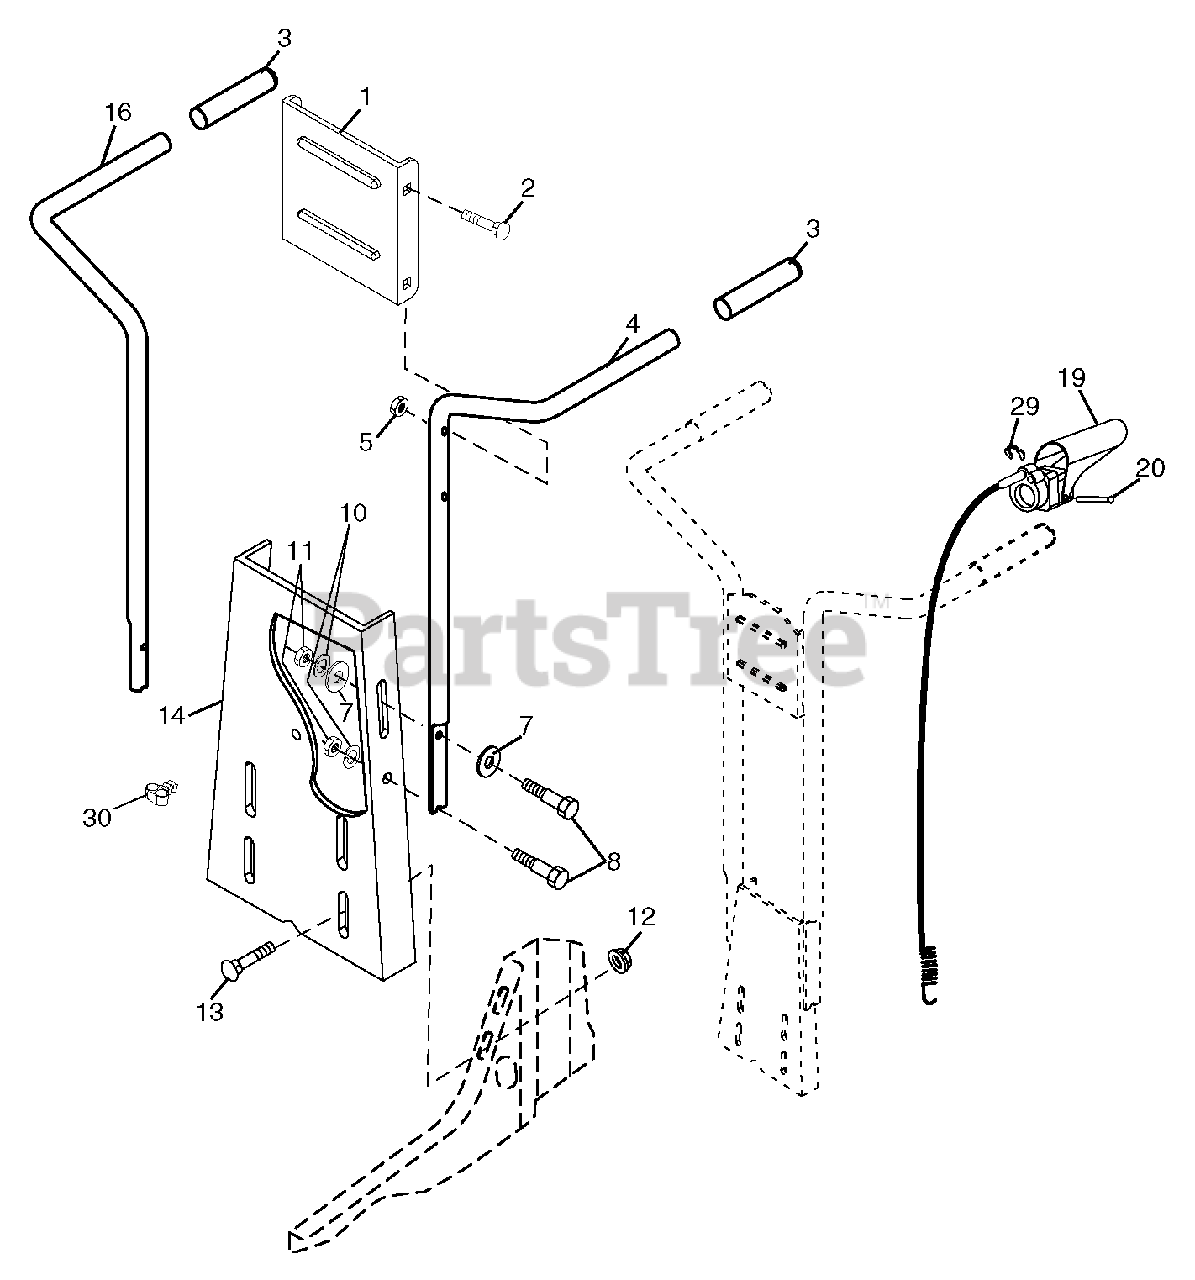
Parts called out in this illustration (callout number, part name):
1	BRACKET.HANDLE.TILLER.YELLOW
3	GRIP.HANDLE.BLACK
4	HANDLE.LH.D.BEND.BLACK
5	NUT.LOCK.5/16-18
7	WASHER
8	BOLT
10	LOCKWASHER
13	BOLT, RDHD SQNK 5/16-18 X 3/4
14	PANEL.HANDLE.RT TILLER.YELLOW
16	HANDLE.RH.D.BEND.BLACK
19	CONTROL ASM.TINE.49.88
20	PIN, PIVOT
29	RETAINING.RING.#5103-25
30	CLIP.ROUTING DUAL
